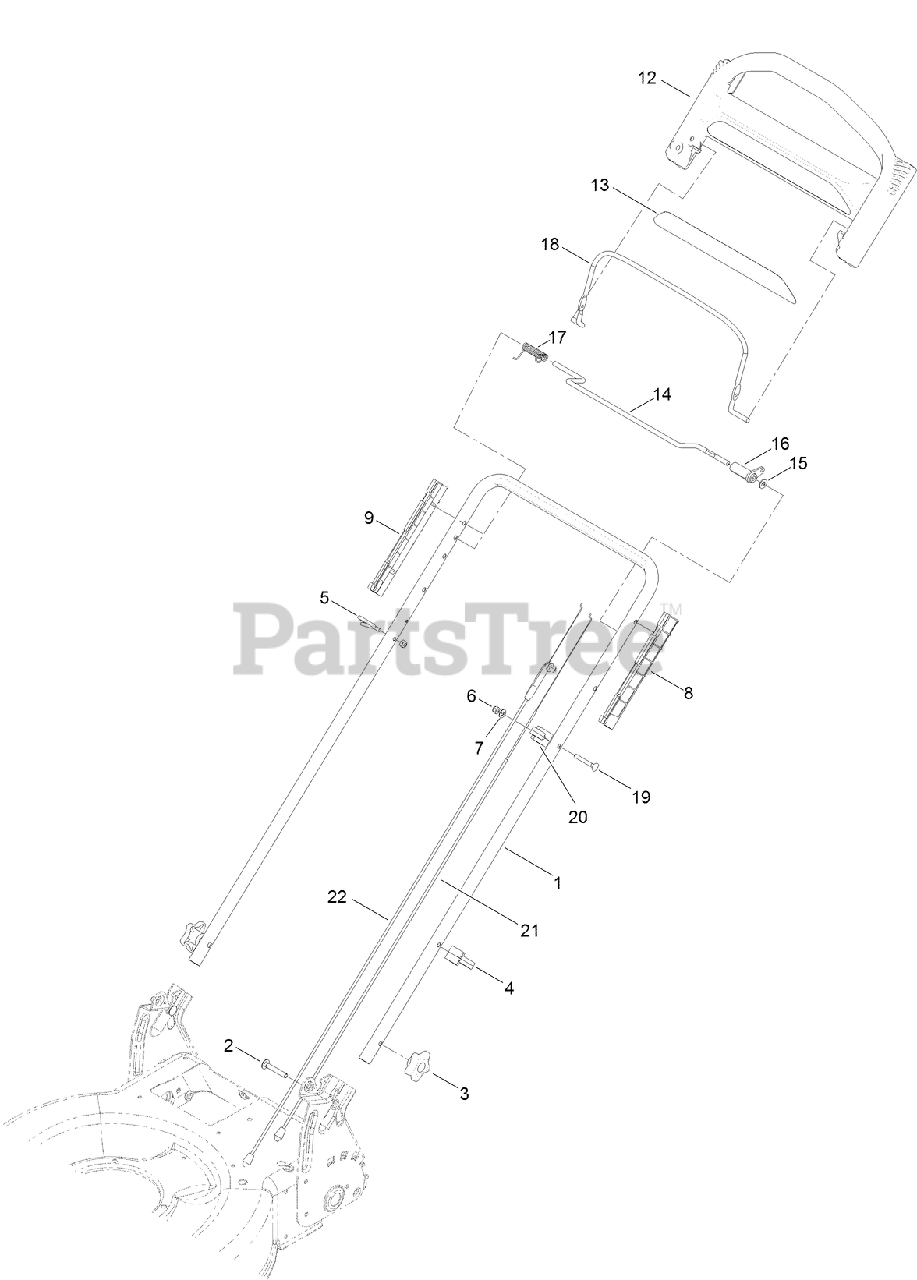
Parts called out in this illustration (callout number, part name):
2	BOLT-CARR
3	KNOB-HANDLE
4	GUIDE-CABLE
5	GUIDE-ROPE
6	NUT-LOCK, NI
7	WASHER-FLAT
8	GUIDE-LH
9	GUIDE-RH
12	HANDLE-CONTROL
15	WASHER-PLAIN
16	LEVER-TRACTION
19	SCREW
21	CABLE-TRACTION
22	CABLE-BRAKE
